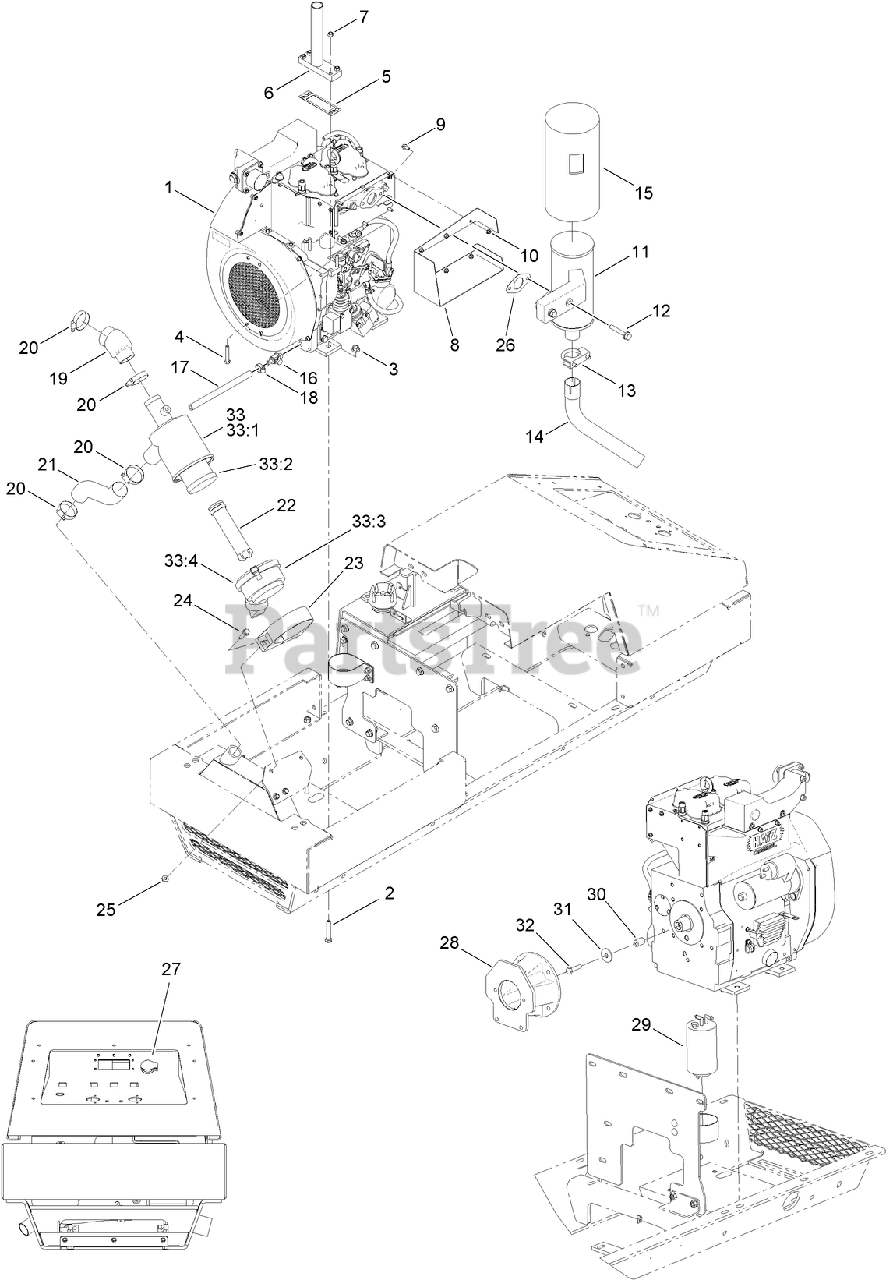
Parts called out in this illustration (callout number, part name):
1	ENGINE-HATZ
2	SCREW-HH
3	NUT-HF
4	Screw-HH
5	GASKET-FILLER, OIL
6	FILLER-OIL
7	NUT-LOCK, NI
8	DUCTING-AIR, OUT EXTENSION
9	SCREW-HHF
10	NUT-HF
11	MUFFLER
12	SCREW-HHF
13	CLAMP-MUFFLER
14	TAILPIPE
15	BLANKET-INSULATION, EXHAUST
16	VALVE-DRAIN, OIL
18	CLAMP-HOSE
19	HOSE-INTAKE, AIR, ENGINE
20	CLAMP-HOSE
21	HOSE-FLEX, VACUUM
22	FILTER-ELEMENT, SAFETY
23	BAND-MOUNTING, AIR CLEANER
24	SCREW-HHF
25	NUT-HF
26	GASKET
27	SWITCH-IGNITION
28	HOUSING-MOUNTING, PUMP
29	FILTER-FUEL/WATER SEPARATOR
30	INSERT-THREAD
31	WASHER-FLAT
32	SCREW-HH
33	AIR CLEANER ASM
33:1	COVER-AIR CLEANER
33:2	ELEMENT-FILTER, AIR
33:3	COVER-LATCHING
33:4	VALVE-VACUATOR
